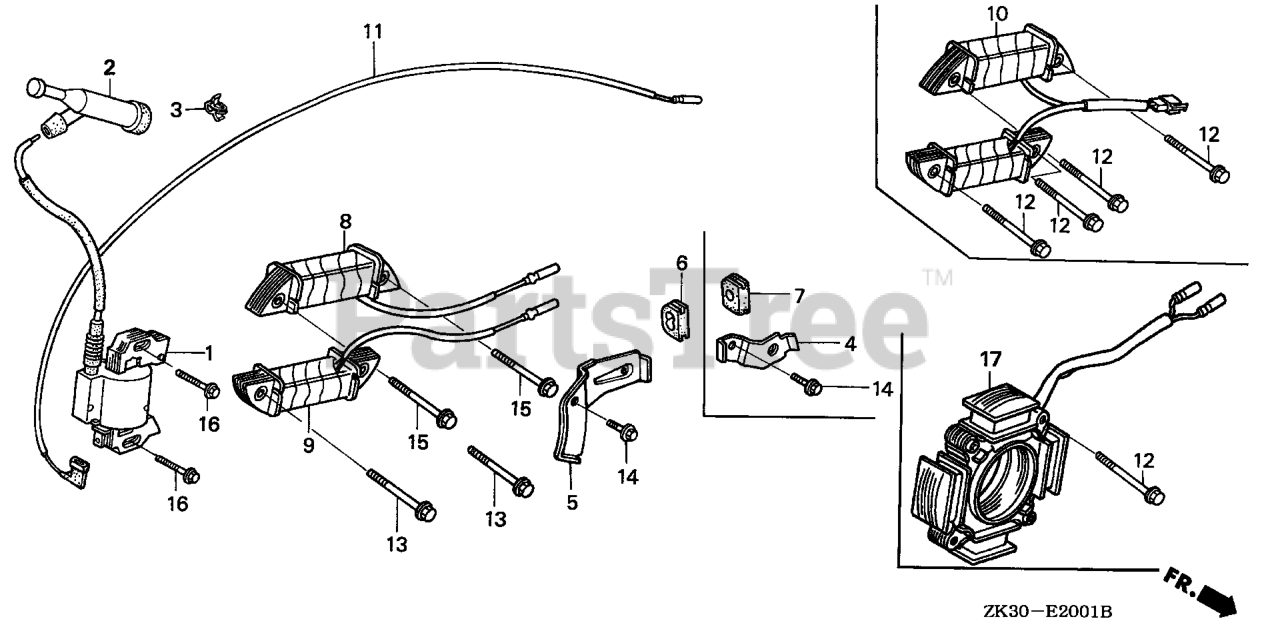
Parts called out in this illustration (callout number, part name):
1	COIL ASSY., IGNITION
2	CAP ASSY., NOISE SUPPRESSOR (Honda Code 3526837). (NICHIWA Y-EZ RTFM256)
4	CLAMP, WIRE
6	GROMMET, WIRE
7	GROMMET, WIRE
11	WIRE, STOP SWITCH (430MM)
12	BOLT, FLANGE (6X40)
14	BOLT, FLANGE (6X12) (CT200)
16	BOLT, FLANGE (6X28) (CT200) Use up to Engine SN 1530314.
17	COIL ASSY., CHARGE (12V/18A)
